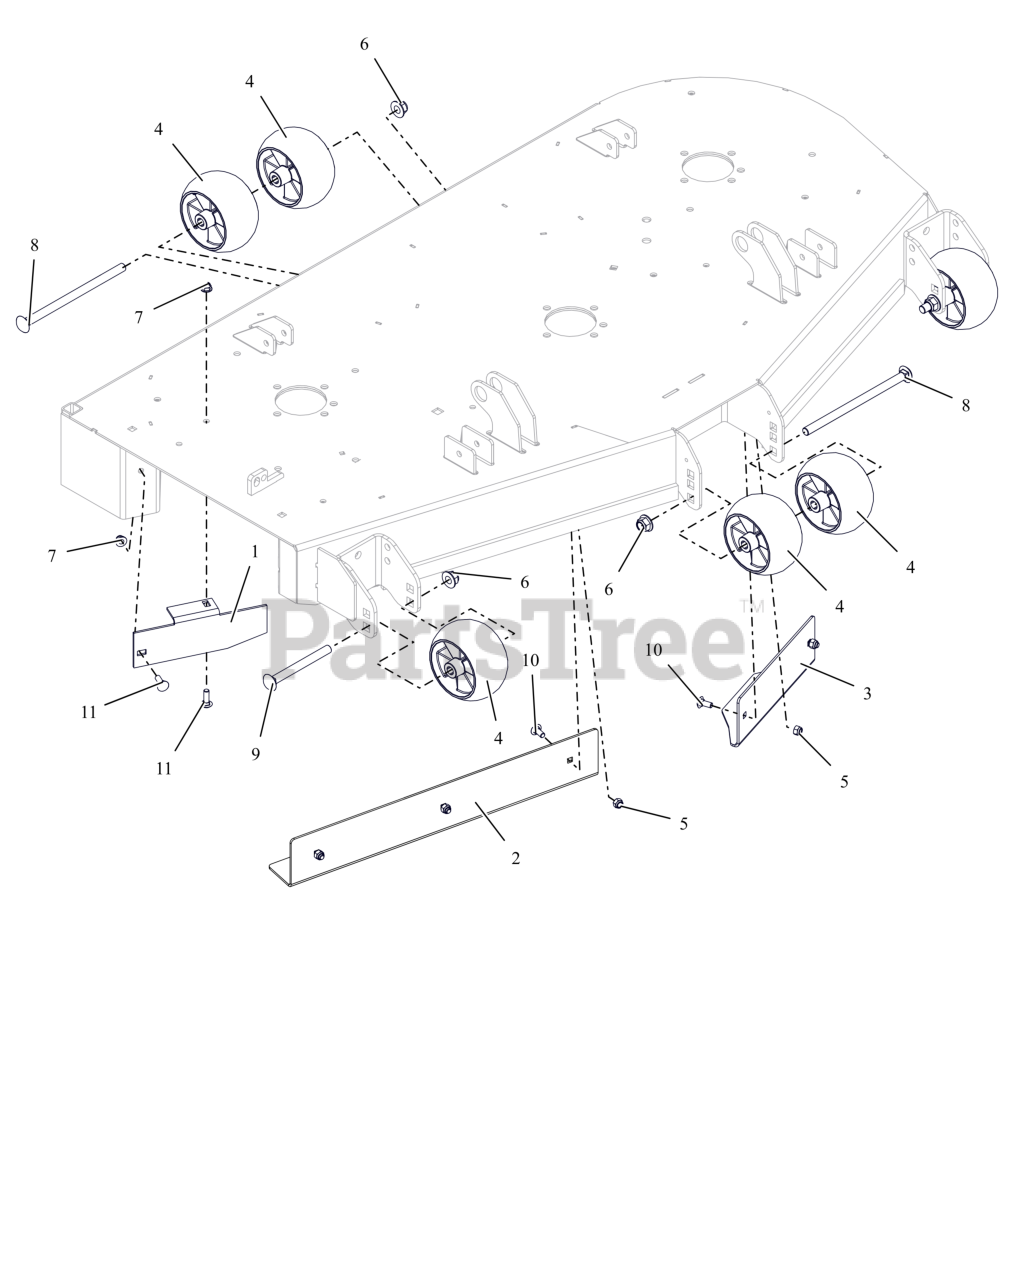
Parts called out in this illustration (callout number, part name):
1	BAFFLE, DISCHARGE, 52"
2	BAFFLE, 52" RH VACUUM (RED)
3	BAFFLE, 52" LH VACUUM (RED)
4	WHEEL, ANTI SCALP - 5X3 CTR W/RIBS
5	NUT,NYL .31-18 G5 ZCC
6	NUT,NYL-FLG .50-13 GF ZCC
7	NUT,NYL-FLG .31-18 GF ZCC
8	BTL,RHSN .500-13 X 8.5S G5 ZCC
9	BLT, RHSN .50-13X5.00 G5 ZCC
10	BLT,RHSN .31-18X.75 G5 ZCC
11	BLT,RHSN .31-18X1.00 G5 ZCC
